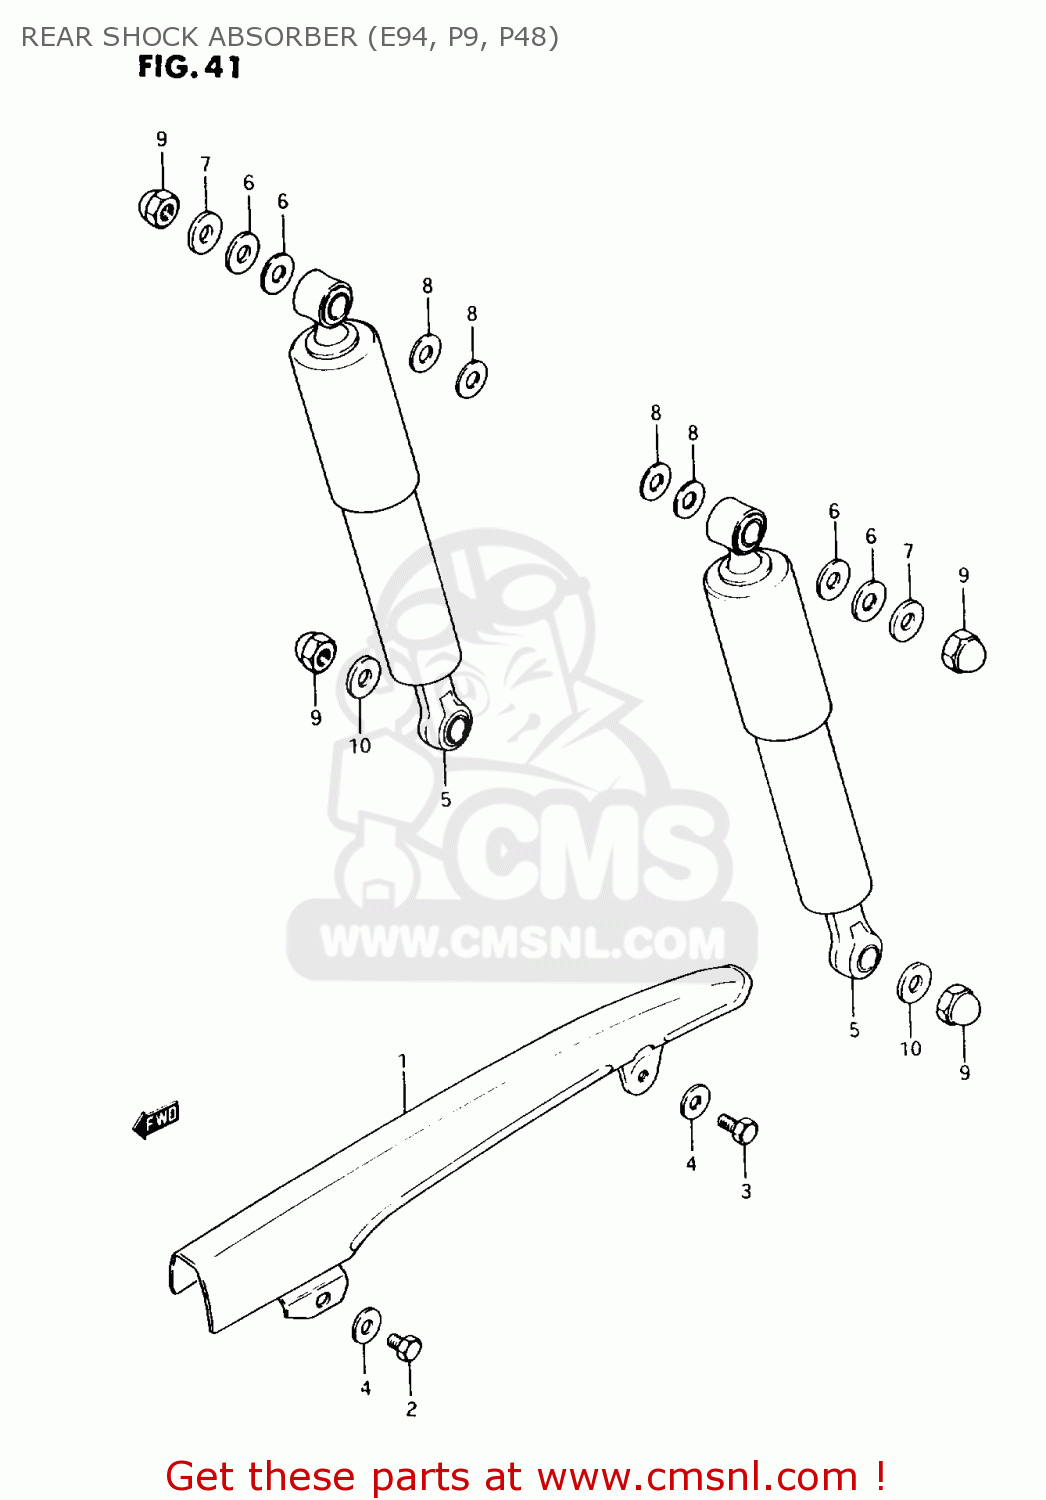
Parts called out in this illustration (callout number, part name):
1	CASE,CHAIN
2	BOLT(6X6)
3	BOLT 6X8
4	WASHER
5	ABSORBER, REAR SHOCK (RED)
6	WASHER
7	WASHER(10.5X24X3.2)
8	WASHER
9	NUT
10	WASHER(10.5X24X3.2)
